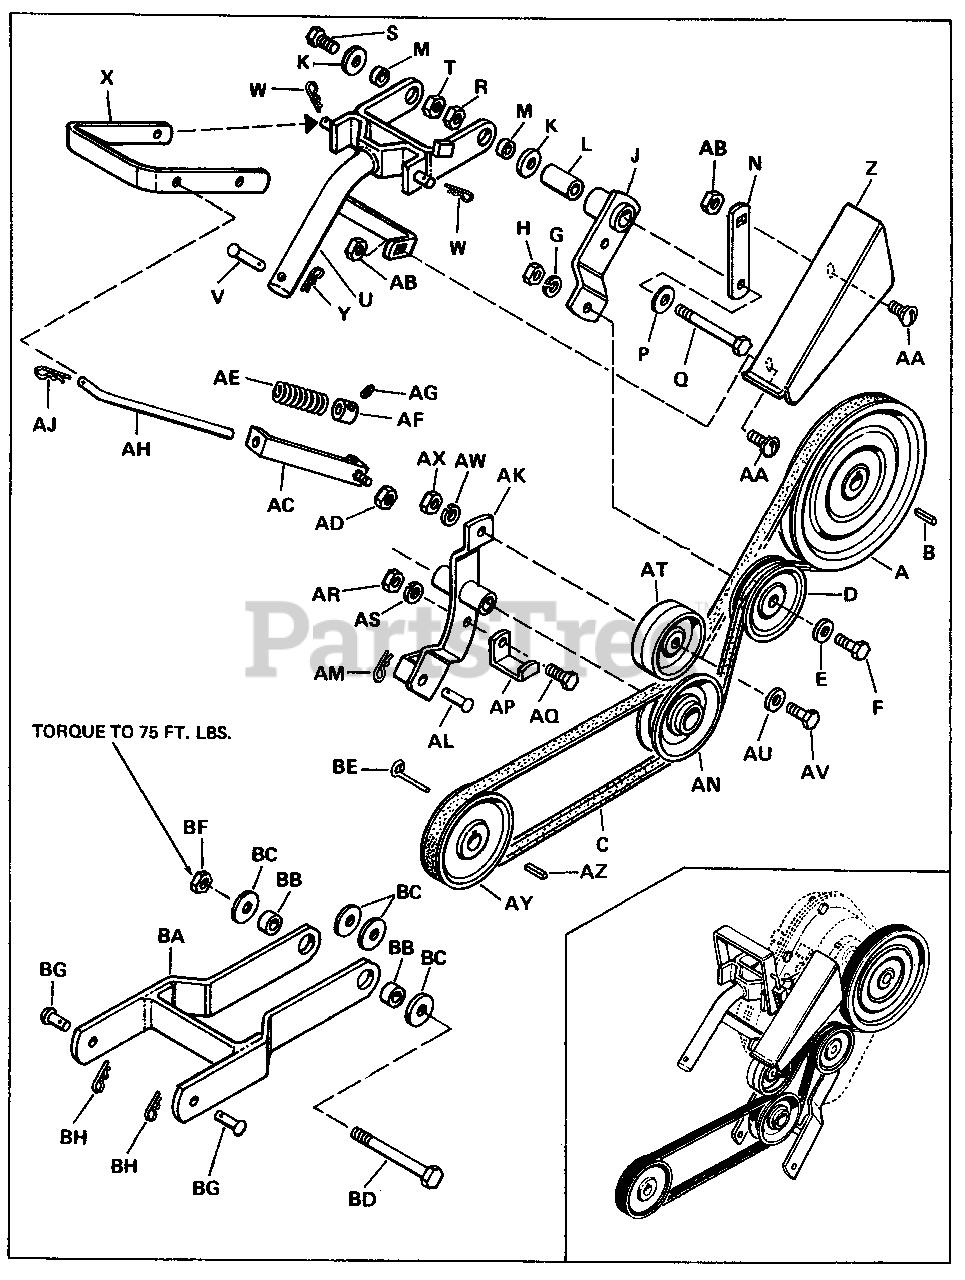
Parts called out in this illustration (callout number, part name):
C	"V" Belt, Sovereign Tractor
E	Plain Washer, 5/16"
F	Hex. Capscrew, 3/8"-16 x 1-1/4"
G	Lock Washer, 3/8"
H	Full Hex. Nut, 3/8"-16
J	Clutch Lever Assembly
K	Plain Washer, 3/8"
N	Rear Support Belt Guard
P	Plain Washer, 7/16"
Q	Hex. Capsrew, Gr. 5, 7/16"-14 x 3-1/2"
R	Full Hex. Locknut, 7/16"
S	Hex. Capsrew, Gr. 5, 7/16"-14 x 1-1/4"
T	Full Hex. Locknut, 7/16"-14
U	Lift Bar Assembly
V	Pin
W	Spring Clip
X	Clutch Handle
Y	Spring Clip
Z	Belt Guard
AA	Carriage Bolt, 5/16"-18 x 1/2"
AB	Nut Whiz Lock, 5/16"-18
AC	Rod Guide Assembly
AD	Full Hex. Nut Lock, 5/16"-18
AF	Set Collar
AG	Cup pt. Sq. Hd. Setscrew, 1/4"-20 x 3/8"
AH	Clutch Rod
AJ	Spring Clip
AK	Arm Idler Assembly
AM	Spring Clip
AN	Idler Pulley
AP	Belt Guard, 1/8 x 1 x 4-1/8"
AQ	Hex. Capscrew, 3/8"-16 x 7/8"
AR	Full Hex. Nut, 3/8"-16
AS	Lock Washer, 3/8"
AT	Idler Pulley
AU	Plain Washer, 5/16"
AV	Hex. Capsrew, 3/8"-16 x 1-1/4"
AW	Lock Washer, 3/8"
AX	Full Hex Nut, 3/8"-16
BA	Frame Assembly
BC	Plain Washer, 1/2"
BD	Hex. Capscrew, 1/2"-13 x 5"
BF	Full Hex. Locknut, 1/2"-13 N.C.
BH	Spring Clip
